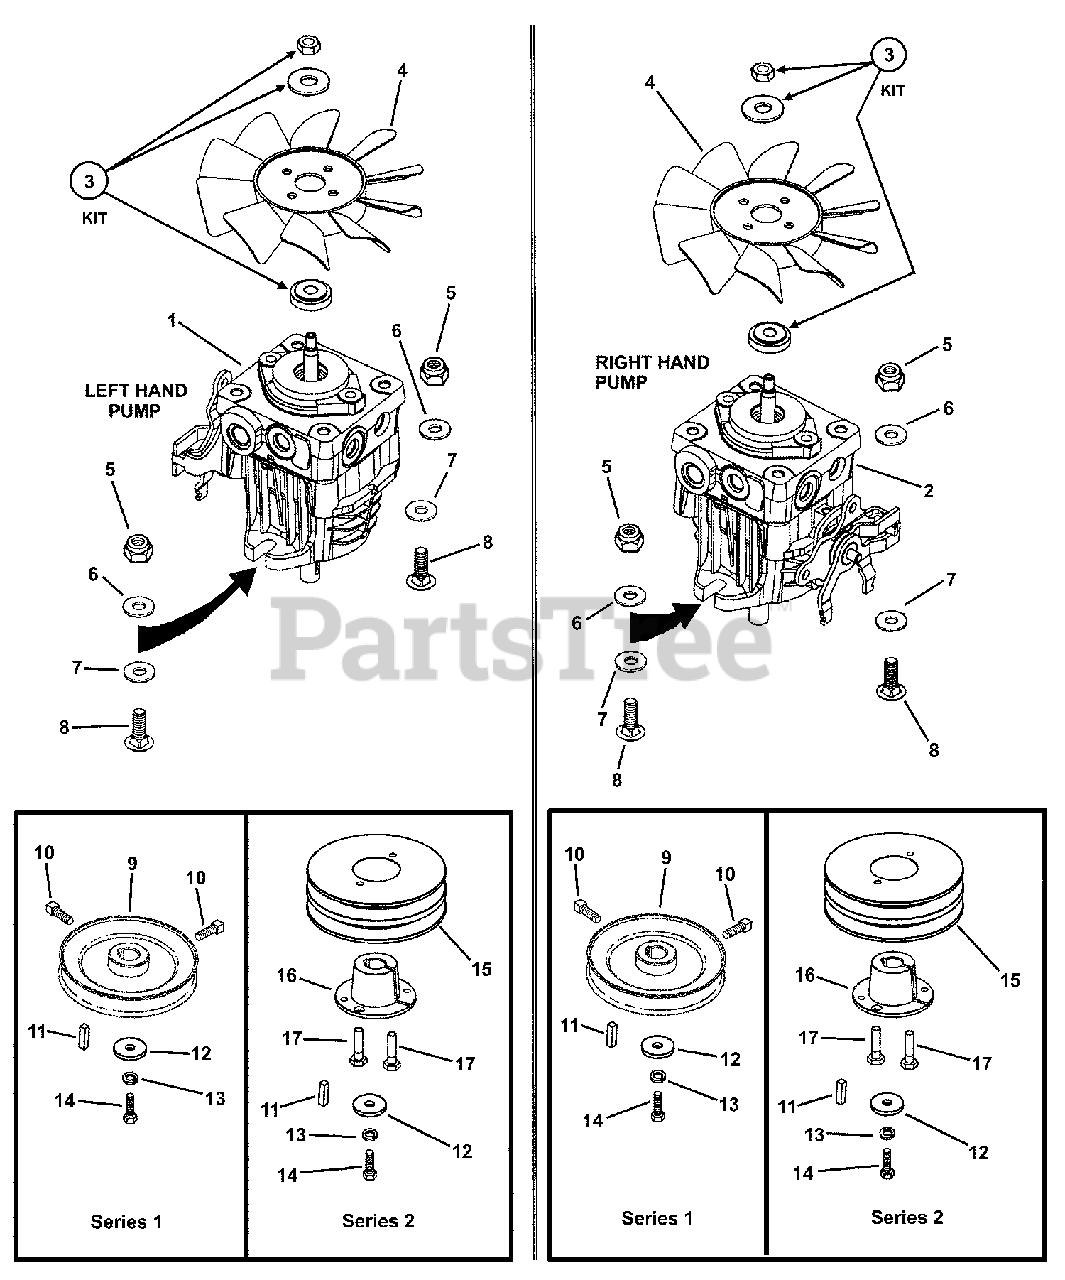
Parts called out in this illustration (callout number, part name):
1	PUMP, Hydro-Gear (BDP-10A-334) Left Hand
2	PUMP, Hydro-Gear (BDP-10A-457) Right Hand
3	HUB KIT for BDP-10A Pump w/Thru Shaft (Incl. 1 ea. of 3 items below)
4	FAN, 7" Nylon, Counter-Clockwise
5	NUT, 3/8-16 HEX NYLON LOCK
6	WASHER, 3/8" Flat
7	RETAINER, 3/8" Bolt
8	BOLT, 3/8-16 x 1-1/4" Short Neck Carriage GR 5
9	PULLEY, Hydro Drive Pump
10	SET SCREW, 1/4-20 x 1/2" Square Head w/Patch
11	KEY, M5 x M20
12	WASHER, .281 x 1.00 x .125 Flat
13	WASHER, 1/4" Split Lock
14	SCREW, M6 1.0X12MM, Hex Head, CZ
15	PULLEY, 4.25 O.D. x 1.375 OA x "H" Tapered Bore
16	PULLEY, "D" Bushing x 15mm Bore
17	SCREW, 1/4-20 x 1" Hex Head Cap, GR 5
